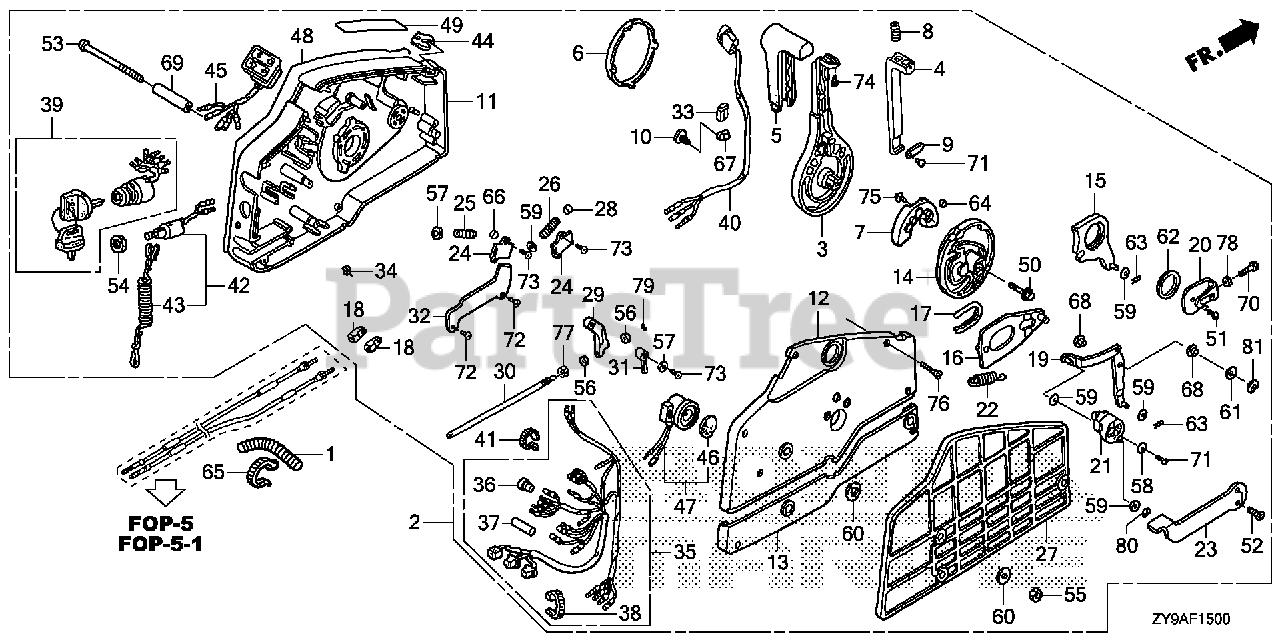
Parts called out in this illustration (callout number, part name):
1	TUBE, CORRUGATED (28MM)
2	BOX ASSY., REMOTE CONTROL (TROLLING CONTROL)(NHK MEC)
2	BOX ASSY., REMOTE CONTROL (NHK MEC)
3	HANDLE, REMOTE CONTROL
4	LEVER, HANDLE LOCK
5	GRIP, REMOTE CONTROL HANDLE
6	CAP, HANDLE
7	BLOCK, NEUTRAL LOCK
8	SPRING, REMOTE CONTROL HANDLE
9	PLATE, LEVER SETTING
10	CLAMP, HARNESS
11	HOUSING, REMOTE CONTROL BOX (A)
12	HOUSING, REMOTE CONTROL BOX (B)
13	HOUSING, REMOTE CONTROL BOX (C )
14	WHEEL, CONTROL
15	ARM, SHIFT LINK
16	PLATE, SLIDING
17	COLLAR, SLIDING PLATE
18	PIVOT, SHIFT
19	ARM, LINK JOINT
20	BRACKET, LINK JOINT
21	WHEEL, ACCELERATOR
22	SPRING, ACCELERATOR WHEEL
23	LEVER, IDLE
24	PLATE, SPRING SETTING
25	SPRING, SHIFT CLICK
26	SPRING, CHOKE RETURN
27	SPACER, REMOTE CONTROL BOX
28	SPACER, CLICK SPRING
29	BLOCK, THROTTLE FRICTION
30	BOLT, FRICTION
31	SPACER, NEUTRAL SWITCH
32	CLAMP, POWER TILT CORD
33	PIPE, HARNESS GUIDE
34	SPACER, CABLE CLAMP
35	CABLE ASSY., REMOTE CONTROL (B) (FOR 4-LED)
36	PLUG, CONNECTOR (INNER) (TROLLING CONTROL)
37	PLUG, CONNECTOR (OUTER) (ENGINE NO.)
38	TIE, CABLE (NATURAL 2.4X92) Use up to Frame SN 1300359.
39	SWITCH ASSY., COMBINATION (SINGLE) (DUAL)
40	SWITCH ASSY., POWER TRIM-TILT
41	BAND (BLACK 3.5X140)
42	SWITCH ASSY., EMERGENCY STOP
43	WIRE, EMERGENCY (SINGLE) (DUAL)
44	CLIP, EMERGENCY LOCK
45	LAMP ASSY., INDICATION
46	PLATE, TURN SIGNAL BUZZER DUAL QTY = (2) (SINGLE)
47	BUZZER, WARNING DUAL QTY = (2) (SINGLE)
48	PLATE, REMOTE CONTROL (COUTION COLOR=RED & YELLOW)
49	MARK, FAST IDLE
50	BOLT, FLANGE (8X35) Use from Frame SN 4800713.
51	SCREW, PAN (6X10)
52	SCREW, FLAT (5X12) Use from Frame SN 4800713.
53	SCREW (6X95)
54	NUT, HEX. (16MM) DUAL QTY = (2) (SINGLE)
55	NUT, HEX. (6MM)
56	WASHER, PLAIN (4MM) Use from Frame SN 4800713.
57	WASHER, PLAIN (5MM)
58	WASHER, PLAIN (5MM)
59	WASHER, PLAIN (6MM) Use from Frame SN 4800713.
60	WASHER (6MM)
61	WASHER, PLAIN (8MM) Use from Frame SN 4800713.
62	WASHER (28MM)
63	PIN, LOCK (6MM)
64	PIN (6X6)
65	BAND, SELF-LOCK Use from Frame SN 3000253.
66	ROLLER, CLICK
67	CLIP, WIRE HARNESS (6.3MM)
68	COLLAR, LINK JOINT
69	COLLAR, DISTANCE (6X10X43.5)
70	BOLT, HEX. (5X16)
71	SCREW, PAN (5X10)
72	SCREW, TAPPING (5X8) (FOR SILVER MUFFLER)
73	SCREW, TAPPING (5X10)
74	SCREW, TAPPING (5X12)
75	SCREW, TAPPING (6X16)
76	SCREW, TAPPING (5X25)
77	NUT, HEX. (6MM)
78	NUT, HEX. (5MM)
79	E-RING (3MM)
80	E-RING (4MM)
81	E-RING (7MM)
